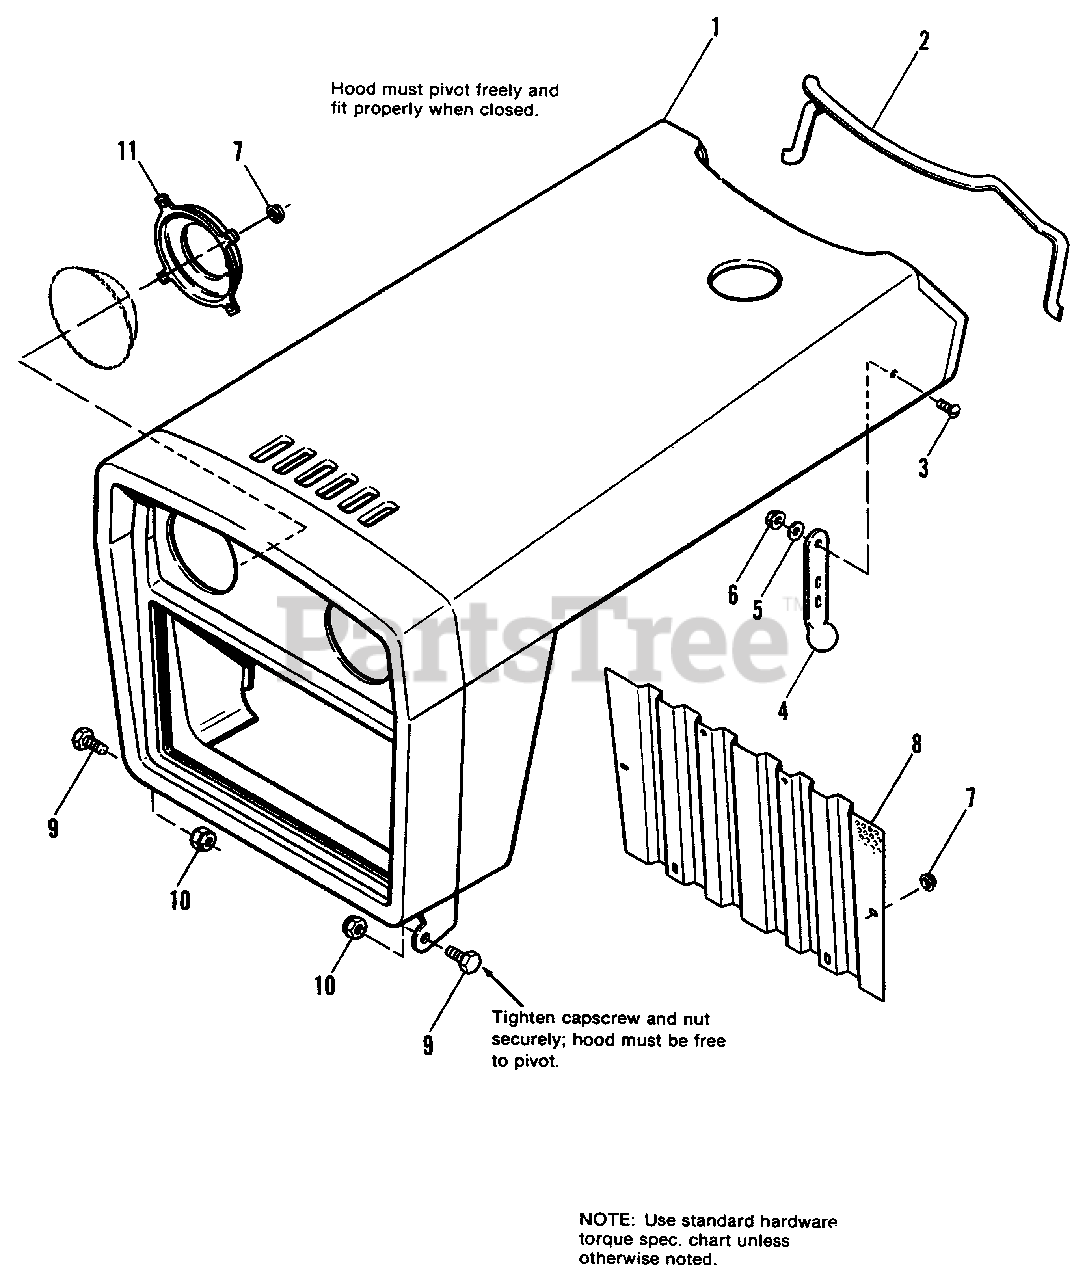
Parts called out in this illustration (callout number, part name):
1	HOOD & GRILLE ASSY.
2	MOULDING, Hood
4	STRAP, Hood
5	WASHER, Special
6	LOCKNUT, Hex, #10-32
7	LOCKNUT, Pal
9	CAPSCREW, Hex Hd., 3/8-16 x 1
10	LOCKNUT, Hex, 3/8-16
11	BRACKET, Headlight Support
